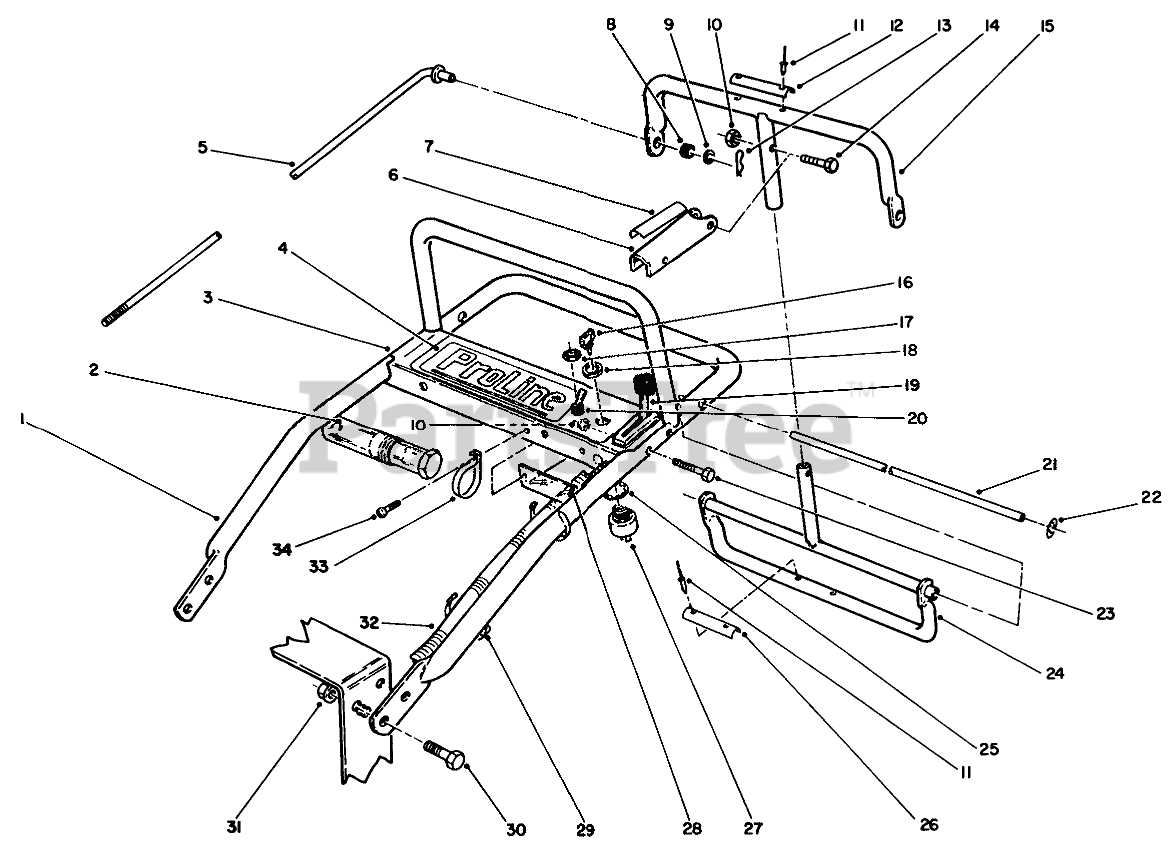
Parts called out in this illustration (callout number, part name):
1	Handle-Upper
2	TUBE-MANUAL
3	CONTROL PANEL B
4	DECAL - CONTROL PANEL
5	CONTROL ROD B
6	Lever-Parking Brake
7	DECAL-LEVER, PARKING
8	GROMMET-RUBBER
9	WASHER-FLAT
10	NUT-LOCK, NI
11	RIVET-BLIND
12	DECAL-CONTROL BAR
13	PIN-COTTER
14	SCREW-SHH
15	Bar-Control
16	KEY-IGNITION
17	NUT
18	NUT-HH
19	CONTROL-THROTTLE
20	Switch
21	PIVOT ROD
22	NUT-PUSH-ON, CIRCULAR
23	SCREW-SHH
24	Control Pivot
25	WASHER-TOOTH, INTERNAL
26	DECAL-REVERSE HANDLE
27	Switch-Off/On (Incl. Ref. #16, 18, & 25)
28	PANEL-BOTTOM
29	TIE-CABLE
30	SCREW-HHF
31	NUT-HF
32	WIRE HARNESS
33	CLAMP-R
34	SCREW-HWHTF
